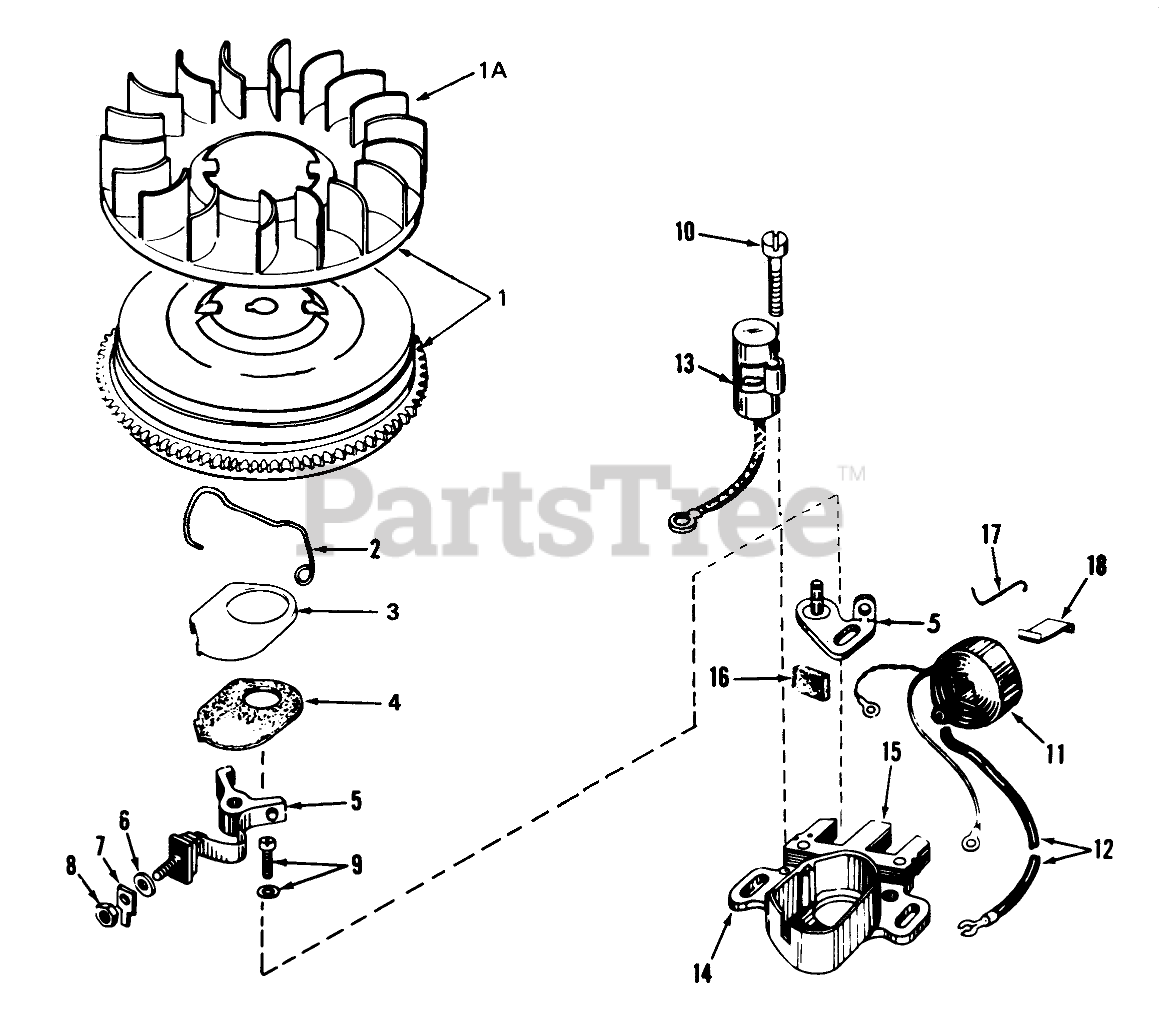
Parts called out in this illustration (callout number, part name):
1	Flywheel (Incl. Ref. #1A)
1A	Fan
2	Spring Breaker Box
3	Cover-Dust
4	Gasket, Dust Cover
5	Breaker Assy.
6	Washer
7	Terminal, Ground
8	DECAL
9	Breaker Screw
10	Condenser Screw
11	Coil Assembly (Incl. Ref. #12)
12	Wire, Lead
13	Condenser
14	Core & Plate
15	Stator Assembly (Incl. Ref. #2 thru 14, 16, 17 & 18)
16	Felt,Cam Wiper
17	Clip, Coil
18	Spring Coil Wedge
